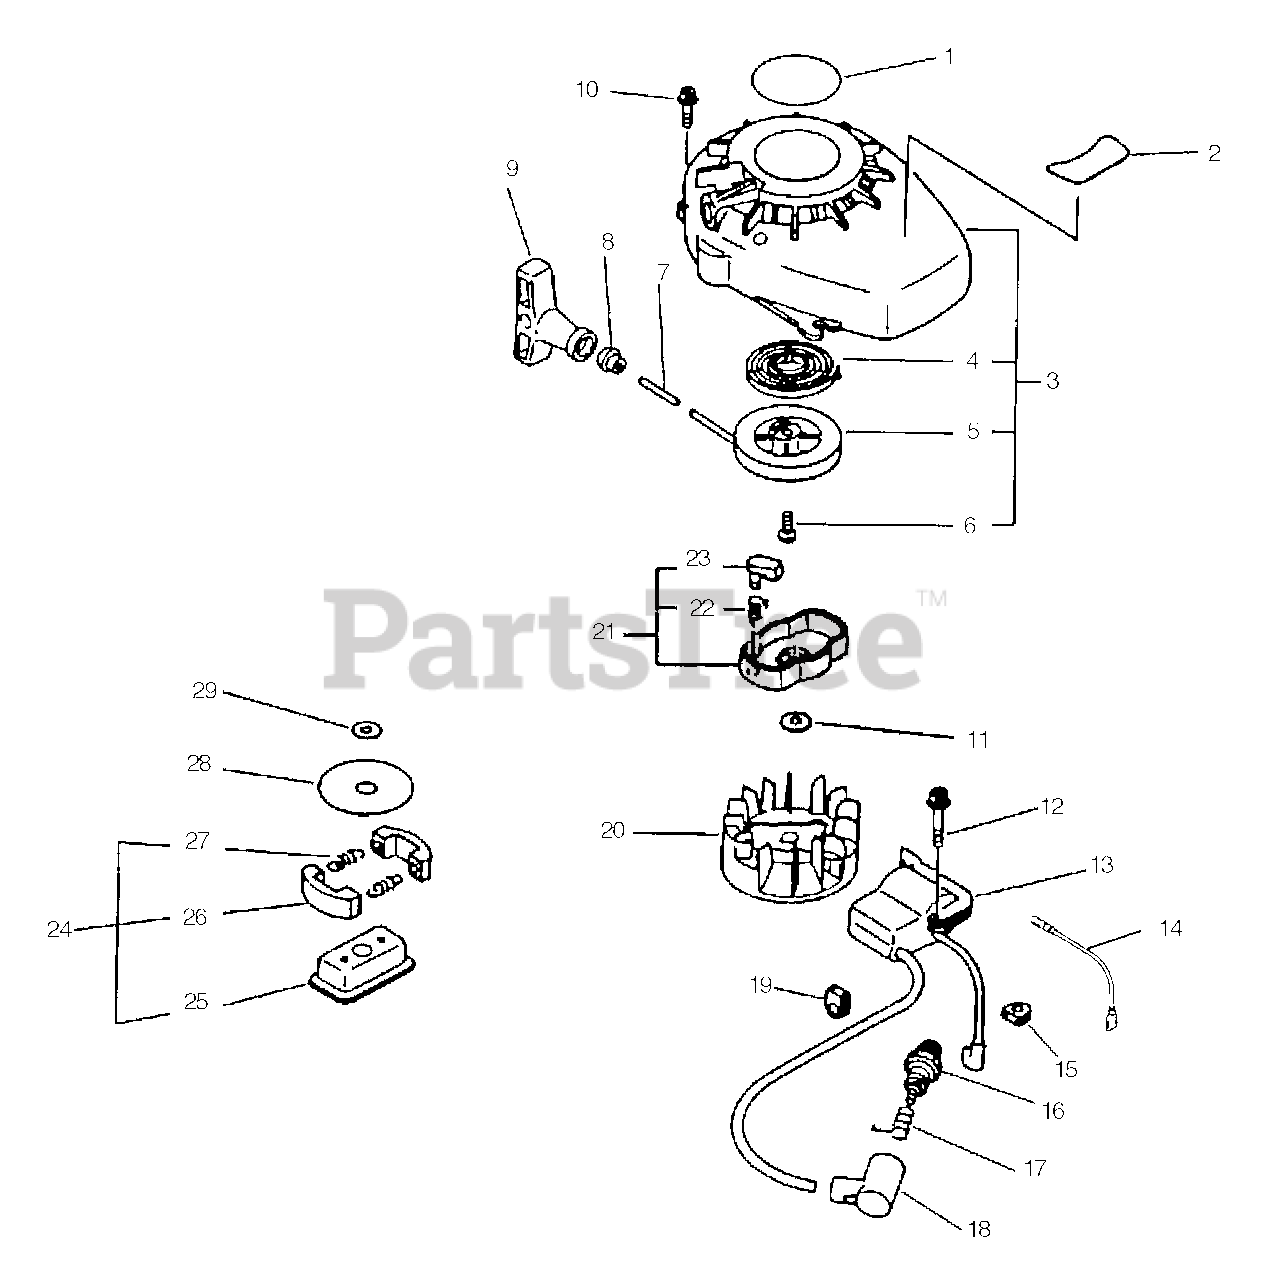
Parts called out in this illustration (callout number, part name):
1	LABEL, HC-1500
2	LABEL - CAUTION
2	LABEL, CAUTION
3	STARTER ASSY
4	SPRING, RECOIL
5	REEL, ROPE
6	SCREW
8	GUIDE, ROPE
9	GRIP, STARTER
10	BOLT 4×16
11	WASHER, SPRING 8
12	SCREW 4×22
13	COIL, IGNITION
14	LEAD
16	SPARK PLUG - BPM-7Y
16	SPARK PLUG - BPMR7A
16	SPARK PLUG - RCJ-8Y
17	TERMINAL, SPARK PLUG
18	CAP, SPARK PLUG
20	FLYWHEEL
21	PAWL ASSY, STARTER
22	SPRING, RETURN
23	PAWL, STARTER - BLACK
24	CLUTCH ASSY
25	BOSS, CLUTCH
25	HUB, CLUTCH
26	SHOE, CLUTCH
27	SPRING, CLUTCH
27	SPRING, TENSION
28	PLATE, CLUTCH
29	WASHER, CLUTCH
